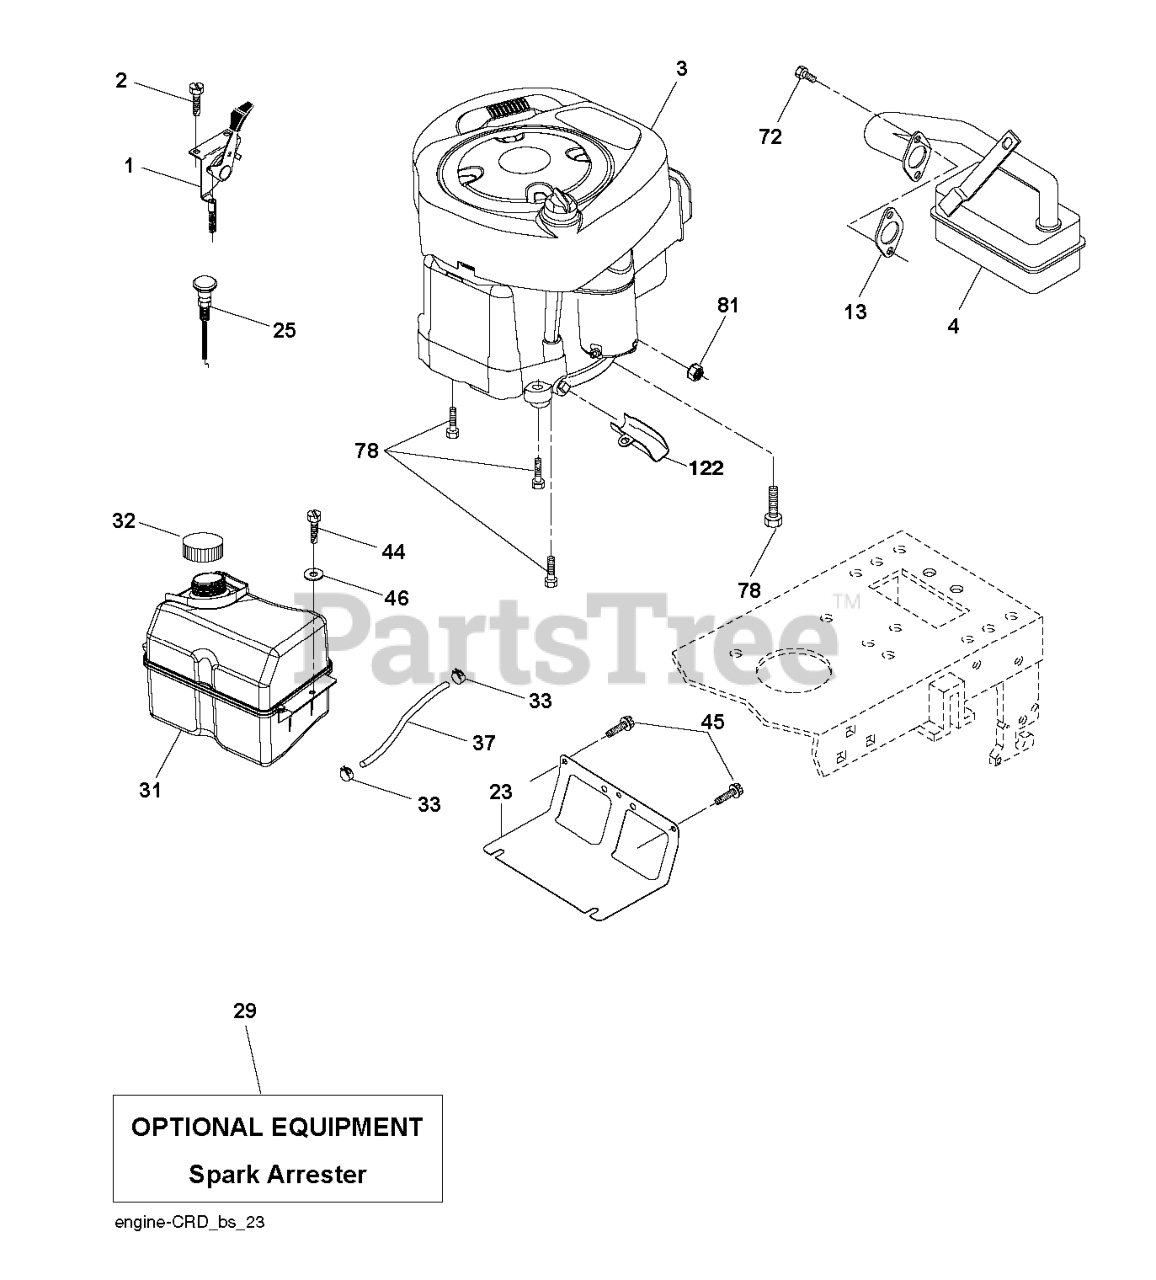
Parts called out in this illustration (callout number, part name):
1	CONTROL.THROTTLE/CHOKE.BLACK
2	SCREW
4	MUFFLER.B&S.MODEL.21.11HP.OHV
13	REPL BY 532 27 22-93
23	SHIELD.BROWNING.DBR.GUARD
25	KNOB.ERGO.EXTENDED.RED (1 2)
29	KIT.SPARK ARRESTOR 794945 B&S
31	TANK.FUEL.FRT.N/CAP.2.0GAL.DAP
32	CAP ASM.FUEL.2.25"FR.
33	HOSE CLAMP
37	LINE.FUEL.20
44	SCREW HEXWSHR 1/4-20X3/4
45	SCREW, 3/8-16X3/4
72	SCREW.SOCKET HD.5/16-1
78	SCREW.3/8-16
81	NUT
122	EXTENSION DRAIN OIL
